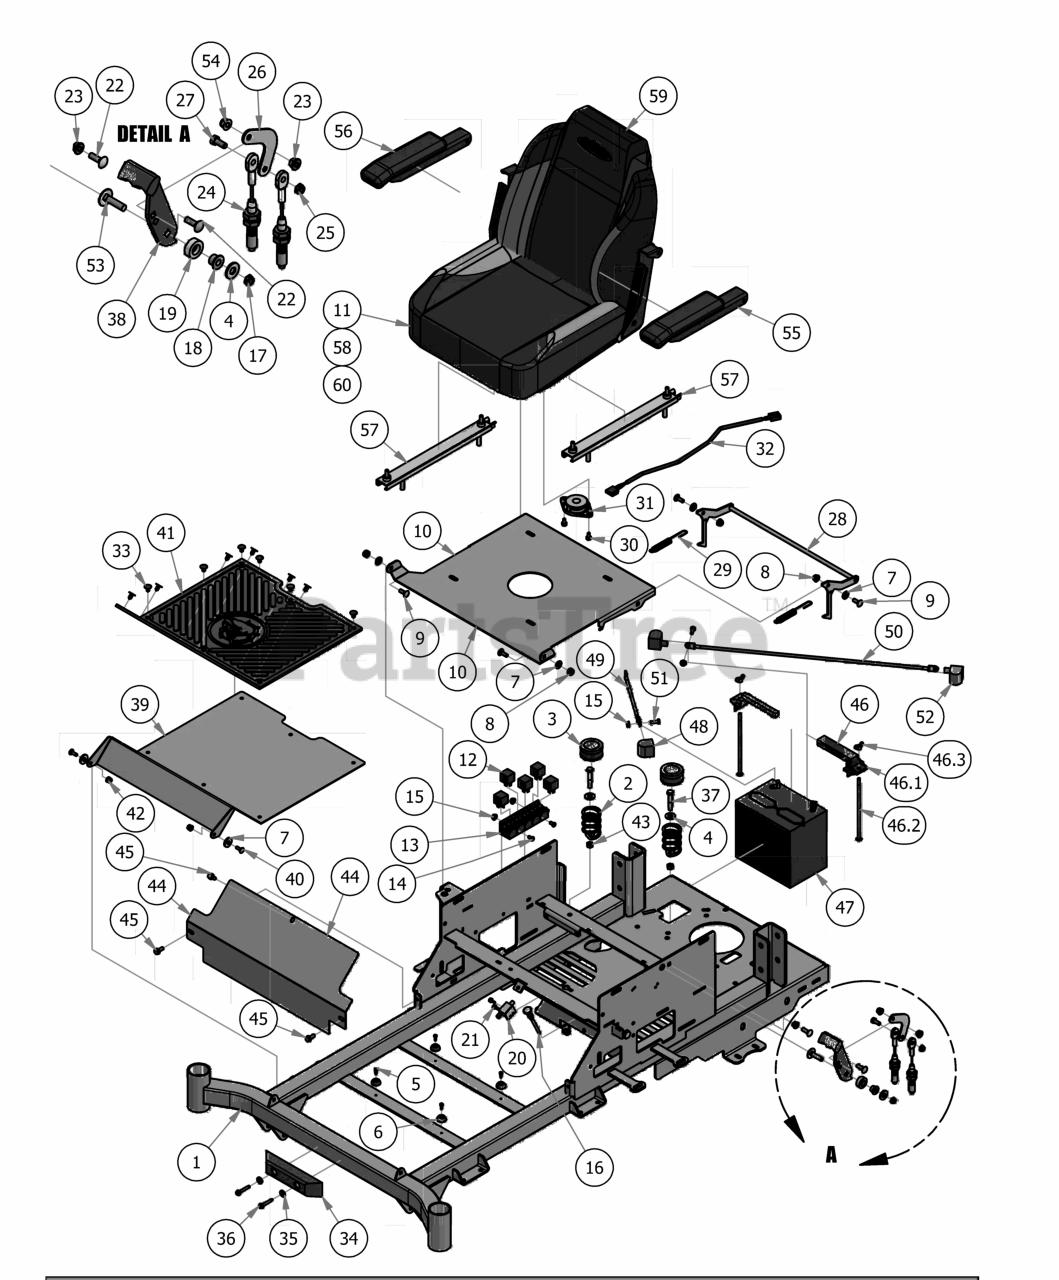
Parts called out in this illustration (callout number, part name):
1	2018 Compact Outlaw Frame
2	Seat Spring
3	Seat Spring Cap Cover
4	3/8" Flat Washer
5	#10 x 1/2" Self Tapping Screw
6	Button Bumper
7	.360 ID Plastic Washer
8	5/16-18 Nylon Flange Nut
9	5/16" x 7/8" Carriage Bolt
10	Seat Plate 2016
11	Compact Outlaw Seat
13	Wire Harness
14	1/4" x 1/2" BS C/S 18-8 SS
15	1/4-20 Hex Flange Nuts Zinc w/Serrations
17	3/8-16 Centerlock Half Nut
18	Bronze Bushing SF-1220-8
19	2015 Brake Lever Spacer
20	Safety Switch
21	12-24x 1/2 HWH Bolt
22	5/16" x 1" Carriage Bolt
23	5/16" Flange Nut w/Serrations
24	Brake Cable
25	5/16-18 Nylock Jam Nut 1/2 Nut
26	Brake Cable Adapter Bracket
27	5/16" x 3/4" Hex Bolt
28	Seat Latch Rod Assembly
29	Seat Latch Spring
30	1/4-20x1/2 HWH Bolt Slot
31	Seat Safety Switch
32	Seat Switch Adapter
33	5/8" Christmas Tree Fastener
34	8" Rubber Bumper
35	5/16" Flat Washer
36	1/4" x 1 1/2" Self Tapping Screw
37	3/8"-16 x 2" Gr 5 Hex Bolt
38	Brake Handle
39	MZ/ZT 2017 Floorboard
40	1/4" x 3/4" Carriage Bolt
41	2017 MZ/ZT Floor Mat
42	1/4-20 Nylon Insert flange Nut
43	3/8-16 Hex Nuts Zinc
44	2017 ZT Cooler Cover
45	5/16 x 3/4 washer head type F screw
46	Hold Down Assembly
46.1	Battery Hold Down
46.2	1/4"-20 x 8 Carriage Bolt
46.3	1/4" Wing Nut
48	Black Boot For Ground Cable
49	Ground Cable
50	24" Red Battery Cable
51	1/4" x 3/4" Hex Bolt
53	3/8" x 1-1/4" Carriage Bolt
54	5/16-18 Nylon Insert Flange Nut (Black Cap)
55	Left Arm Rest
56	Right Arm Rest
57	Seat Rails
59	Seat Back Cover
60	Seat Bottom Cover
